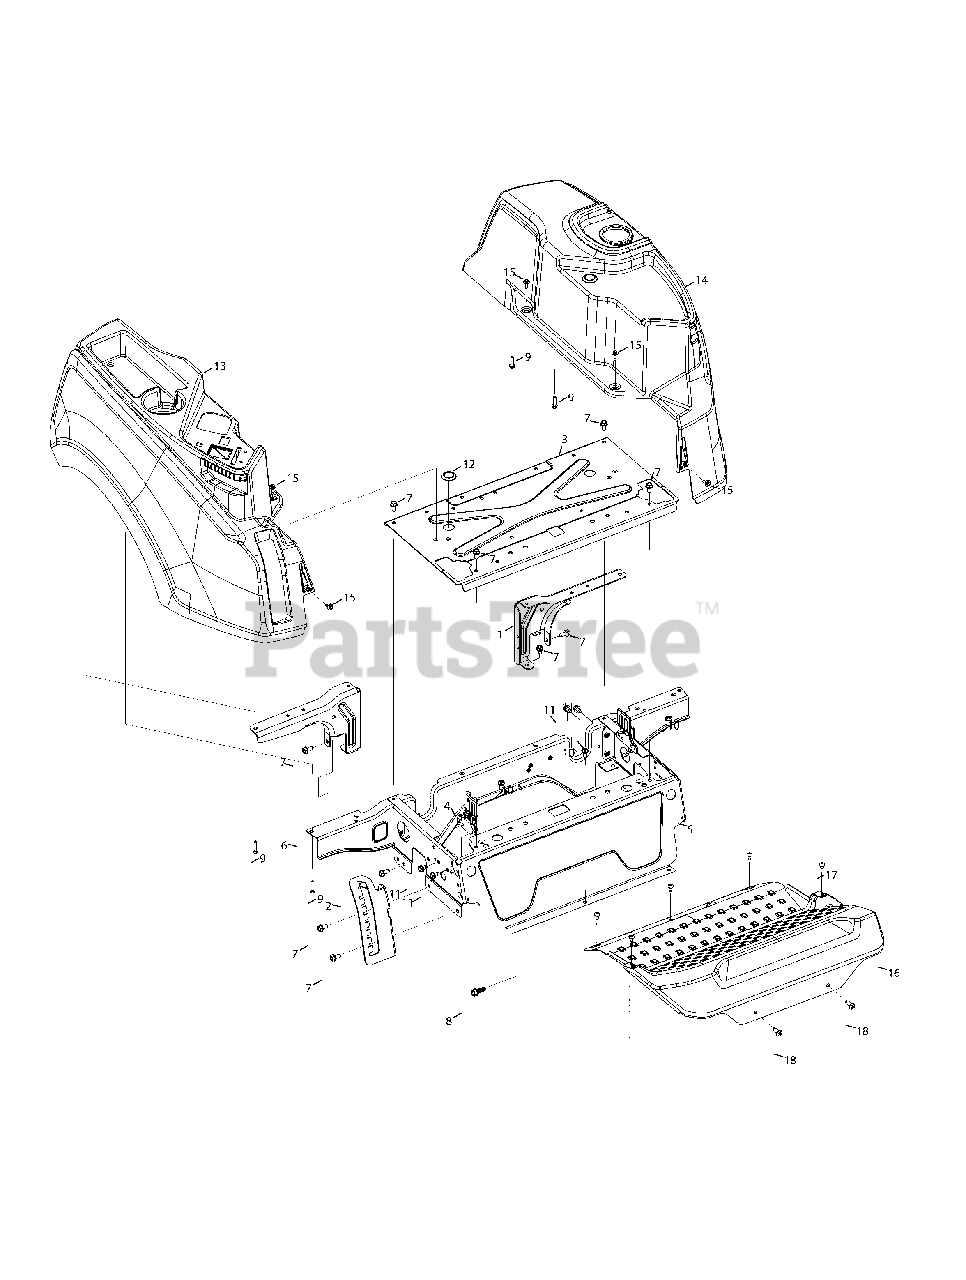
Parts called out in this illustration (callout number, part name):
1	BRACKET, Rear Tank
2	BRACKET, Tank Rear
3	PLATE, Seatbox Top
4	BRACKET, Lapbar Brace
5	FRAME, Seat
6	BRACE, Rear Saetbox Brace
7	SCREW, 5/16-18 X .750, Hex Washer
8	CAPSCREW, Hex Head, 3/8-16 x 1, GR5
9	SCREW, 5/16-14 X 1.0
10	SCREW, 5/16-18 X .750
11	SCREW, 5/16-18 X .500
13	CONSOLE, (RH)
14	CONSOLE, (LH)
15	SCREW, M6-1 .368 X.115, Shoulder
16	FLOORBOARD
17	SCREW, 1/4-20 X .50
18	SCREW, 5/16-18, 0.750, Self-Tapping
